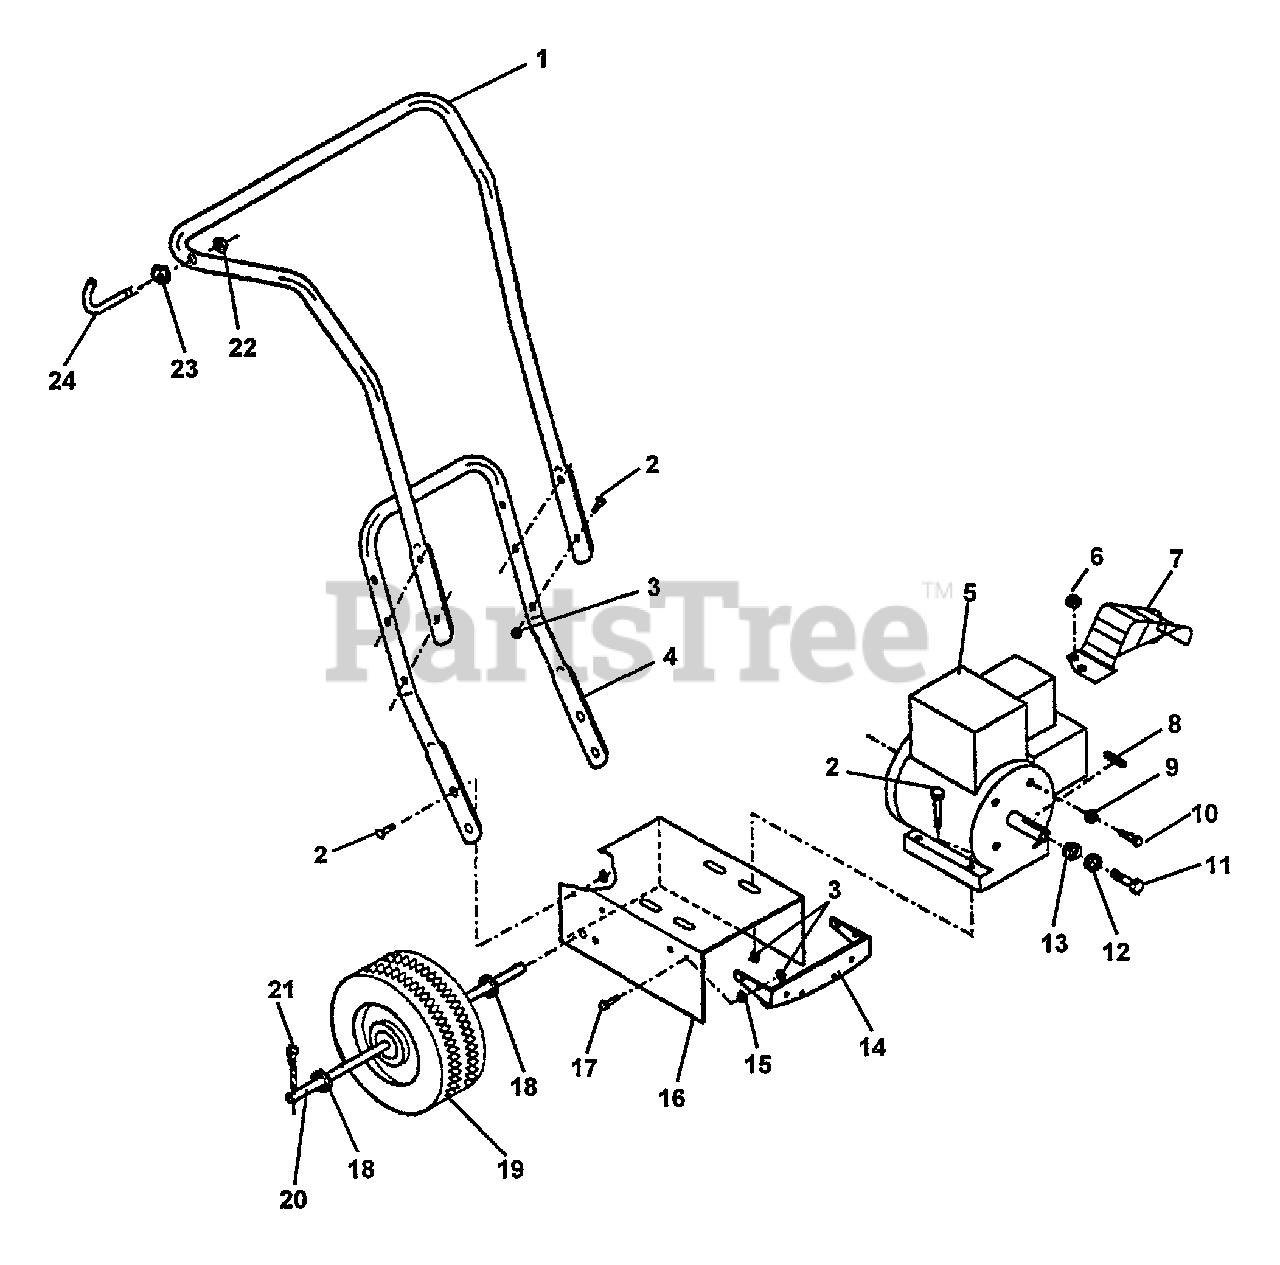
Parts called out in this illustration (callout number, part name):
5	BRIGGS & STRATTON ENGINE 5 HP
9	LOCKWASHER - 5/16"
10	BOLT - 5/16-24 X 1"
13	WASHER - 5/16"
17	BOLT - 5/16-18 X 1-1/4"
18	WASHER - 5/8"
21	PIN, SPLIT - 1/8 X 1-1/4"
